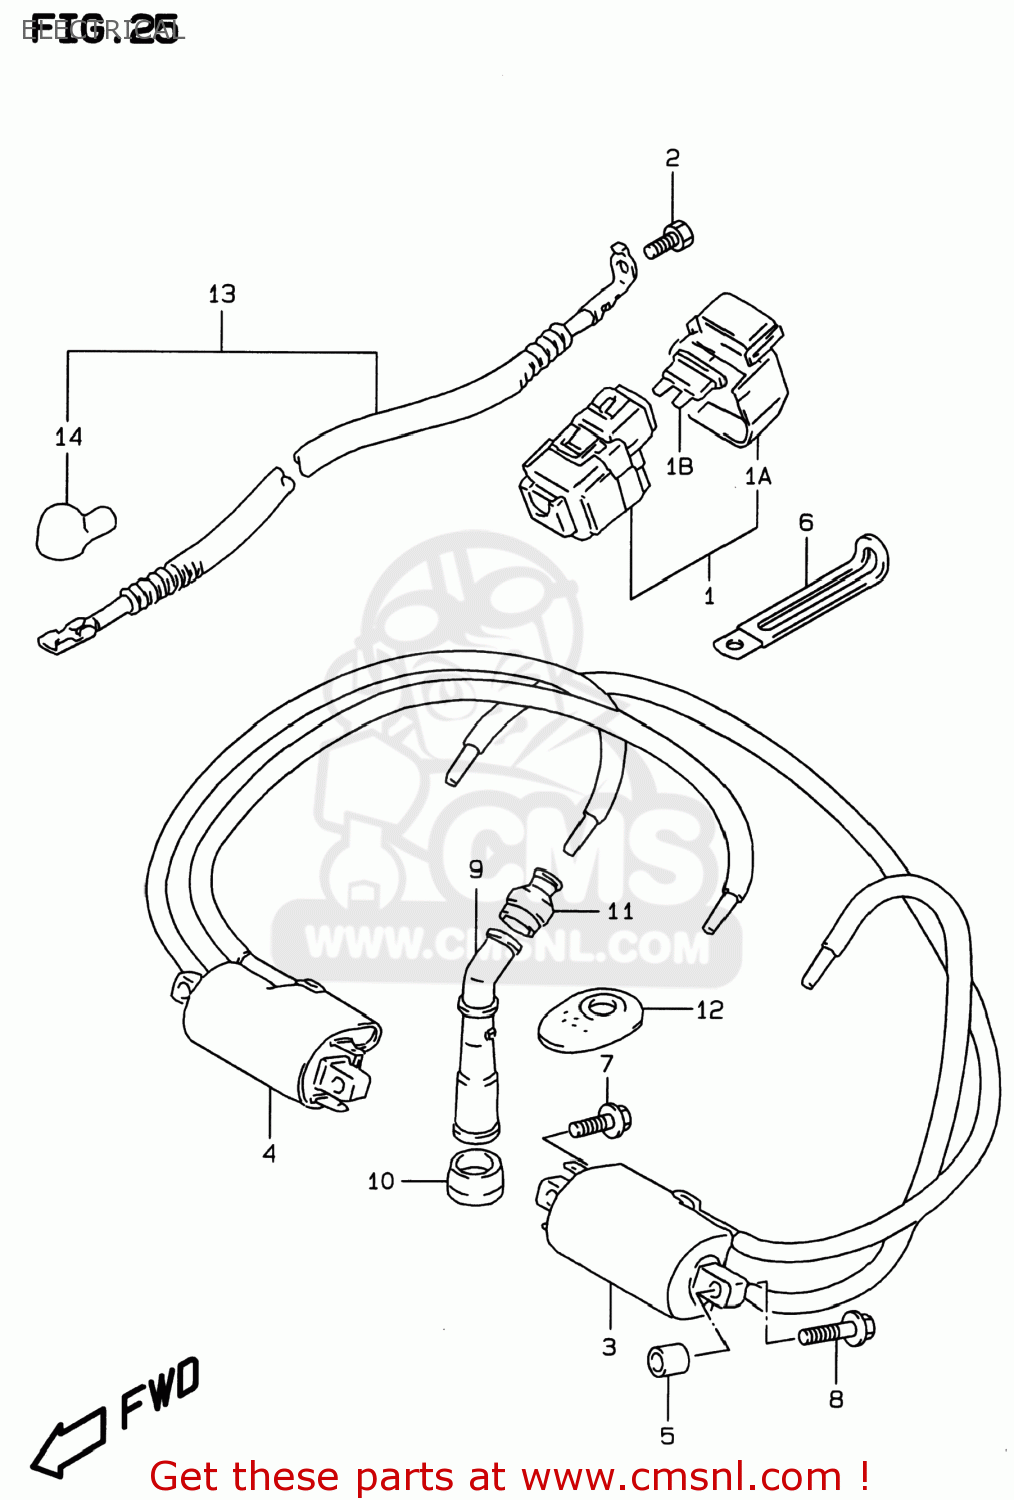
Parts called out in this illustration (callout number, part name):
1	RELAY ASSY,STARTING MOTOR
1A	COVER,STARTER RELAY
1B	FUSE(30A)
2	SCREW(6X8)
3	COIL ASSY,IGNITION
4	COIL ASSY,IGNITION
5	SPACER(6X12X10)
6	CLAMP(L:65)
7	BOLT
8	BOLT
9	CAP,SPARK PLUG
10	SEAL,SPARK PLUG CAP
11	SEAL,HIGH TENSION CORD
12	COVER,SPARK PLUG CAP
13	WIRE,STARTER MOTOR LEAD
14	CAP,STARTER MOTOR TERMINAL
